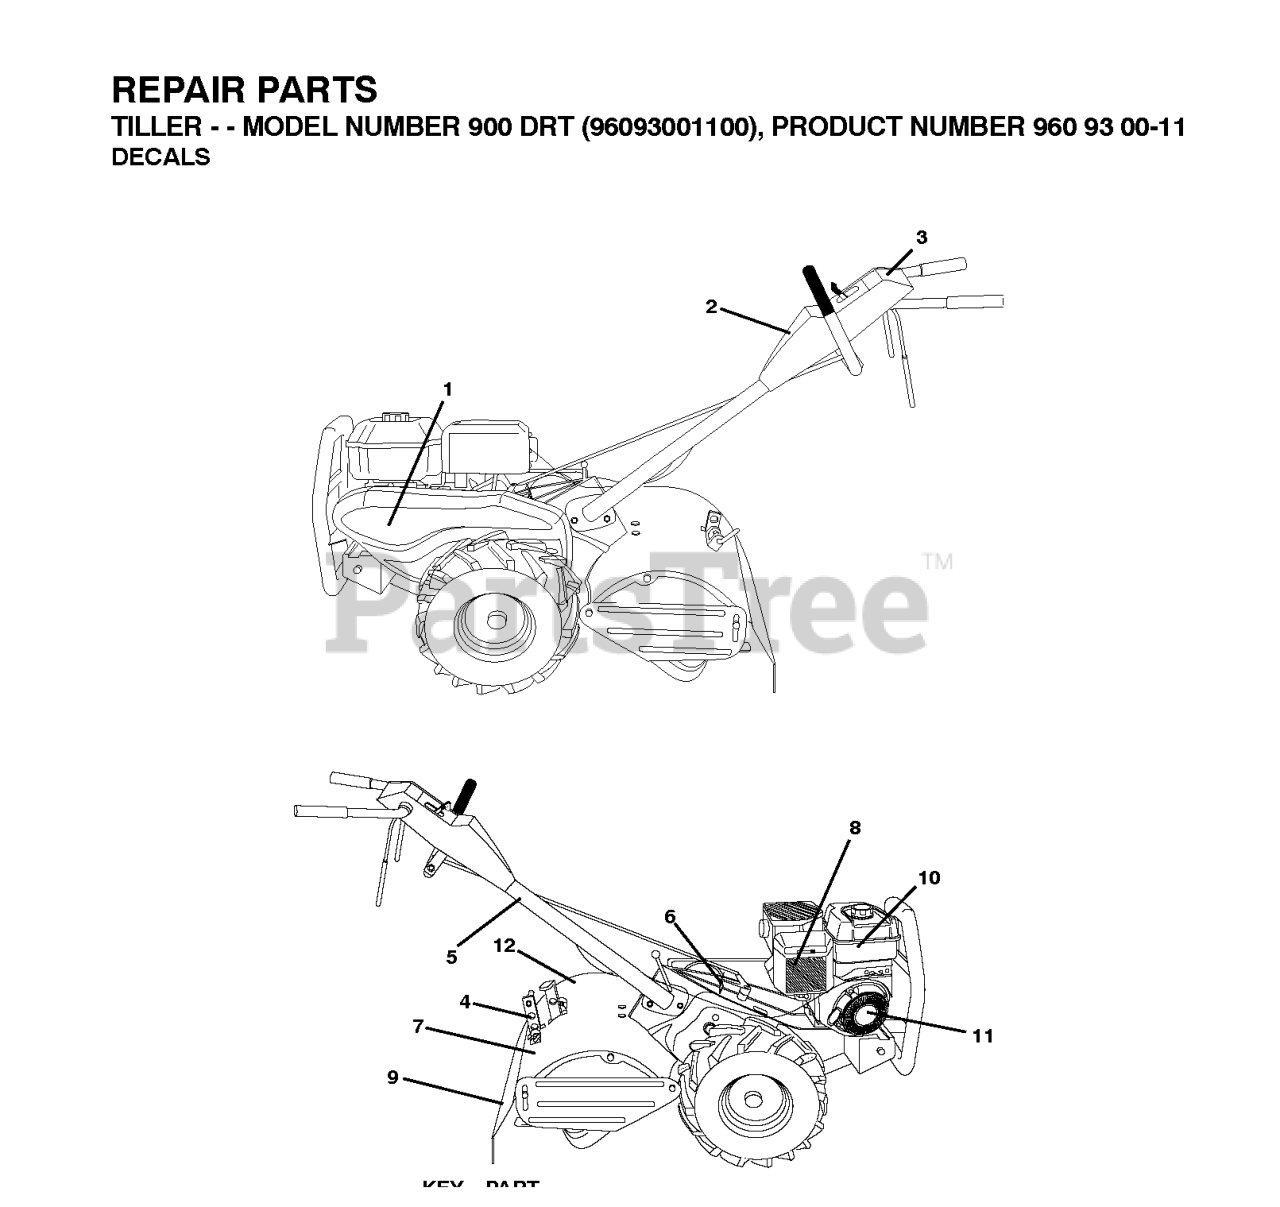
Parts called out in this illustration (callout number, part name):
1	RP.DECAL.BADGE.170MM.TEXTLOGO
2	DECAL.CNSL.DRT900/HUSQVARNA
3	DECAL.TILLER.CNSL.INS.
4	DECAL.SHIELD.TN.DRT17.HUSQ.008
5	DECAL TI (2 2)
6	DECAL.SHIFT.INDICATOR.DRT
7	DECAL.REVERSE.HUSQ
8	DECAL.B&S.900.A/S.C (279005)
9	DECAL.DRT.WARN.ENG/F
10	DECAL.B&S.900.TANK.REF.276991
12	DECAL.FORWARD.HUSQ
